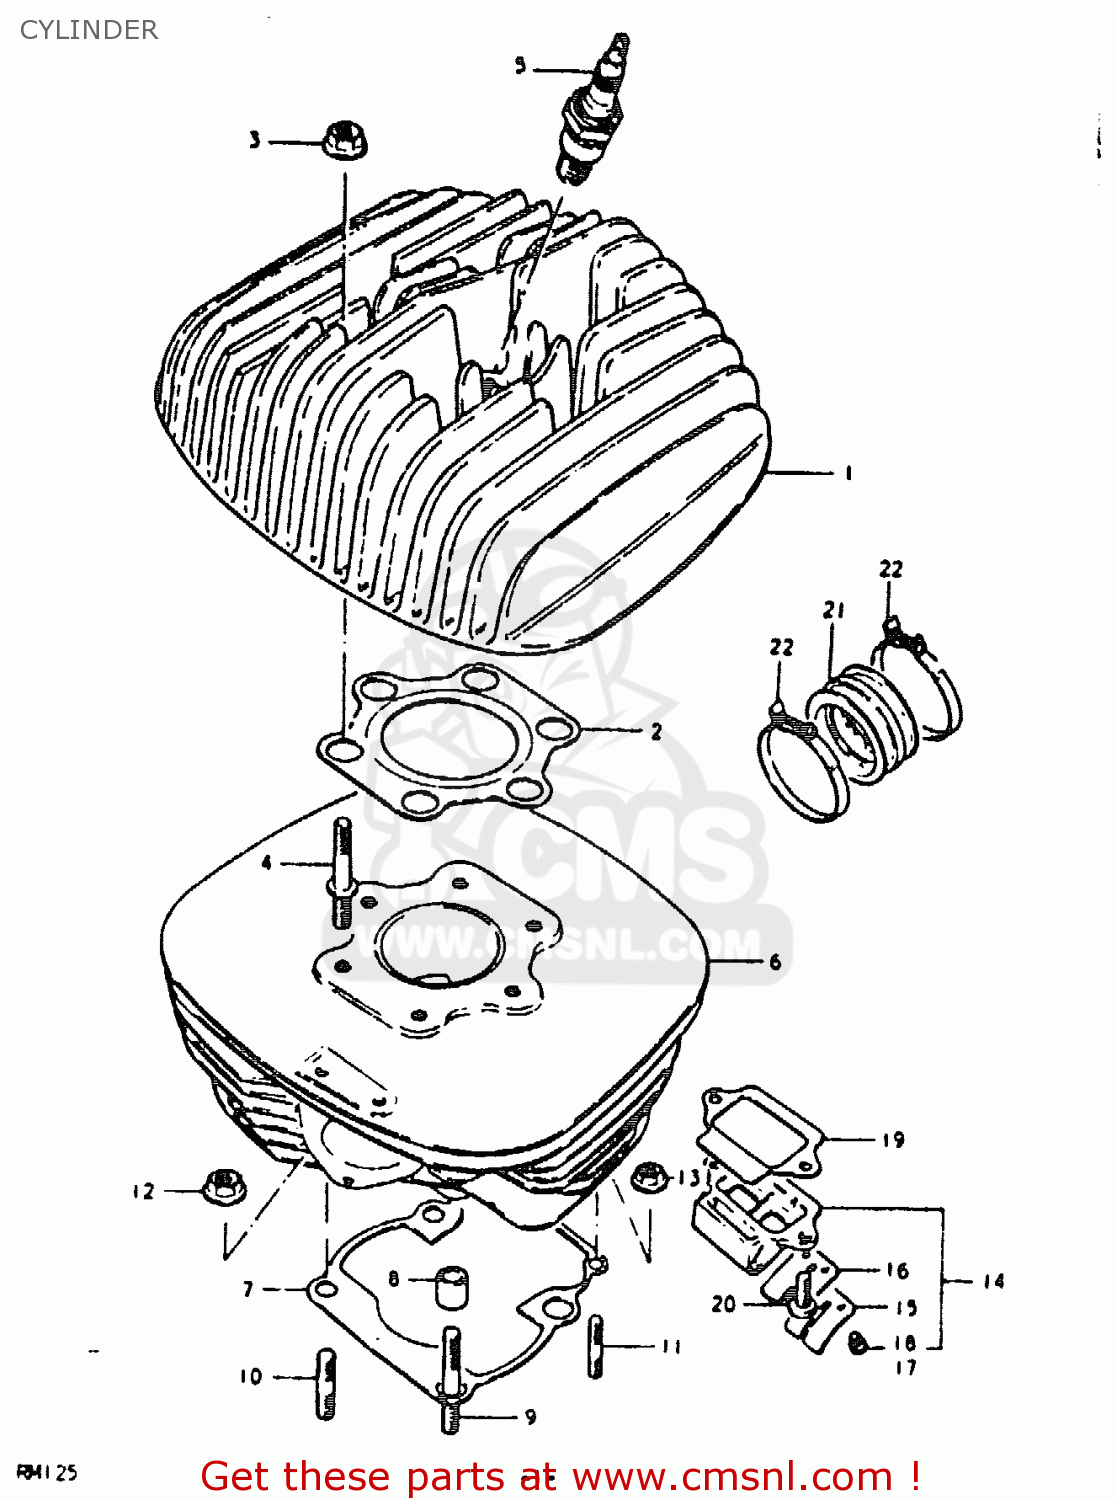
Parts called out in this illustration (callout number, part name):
1	HEAD,CYLINDER
2	GASKET,CYLINDER HEAD (NAS)
3	NUT
4	BOLT,STUD
5	PLUG,SPARK(NGK B-8EN)
6	CYLINDER
7	GASKET,CYLINDER (MCA)
8	PIN
9	STUD 8X40
10	STUD 8X25
11	STUD 6X20
12	NUT
13	NUT
14	VALVE ASSY,REED
15	STOPPER,REED VALVE
16	VALVE,REED
17	SCREW
18	LOCK WASHER
19	GASKET,REED VALVE (MCA)
20	SCREW
21	PIPE,INTAKE
22	CLAMP
